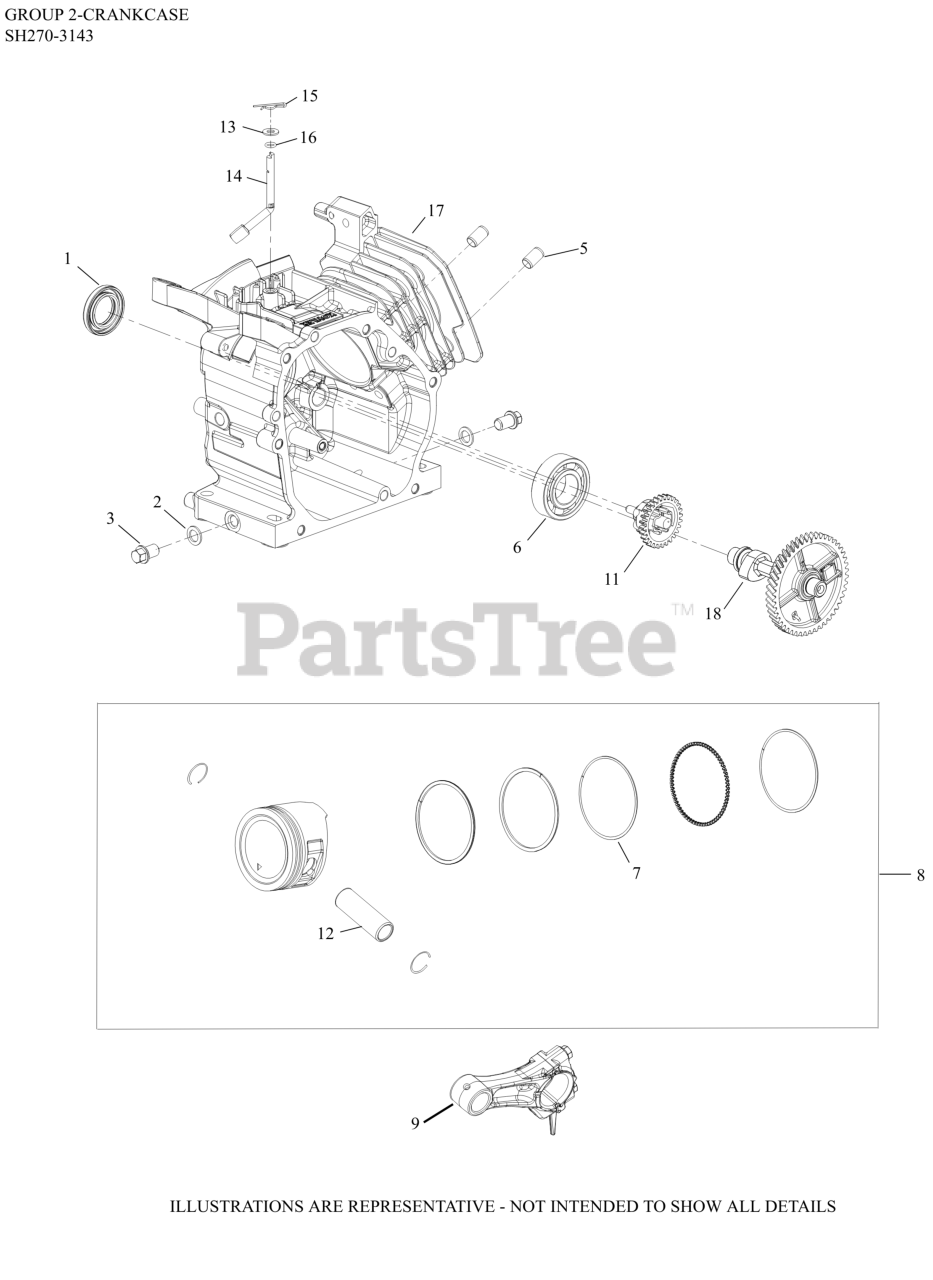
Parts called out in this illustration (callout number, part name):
1	SEAL - USE 17 032 29-S
2	WASHER, DRAIN PLUG
3	KIT, DRAIN PLUG
5	DOWEL, CYLINDER HEAD
6	BEARING, BALL
8	KIT, PISTON (STD)
9	ROD, CONNECTING ASSEMBLY
11	GOVERNOR ASSEMBLY
12	PIN, PISTON
13	WASHER, FLAT (DIA 13mm O.D.)
14	CROSS SHAFT
15	CLIP, GOVERNOR SHAFT
17	CRANKCASE
18	CAMSHAFT, ASSEMBLY
